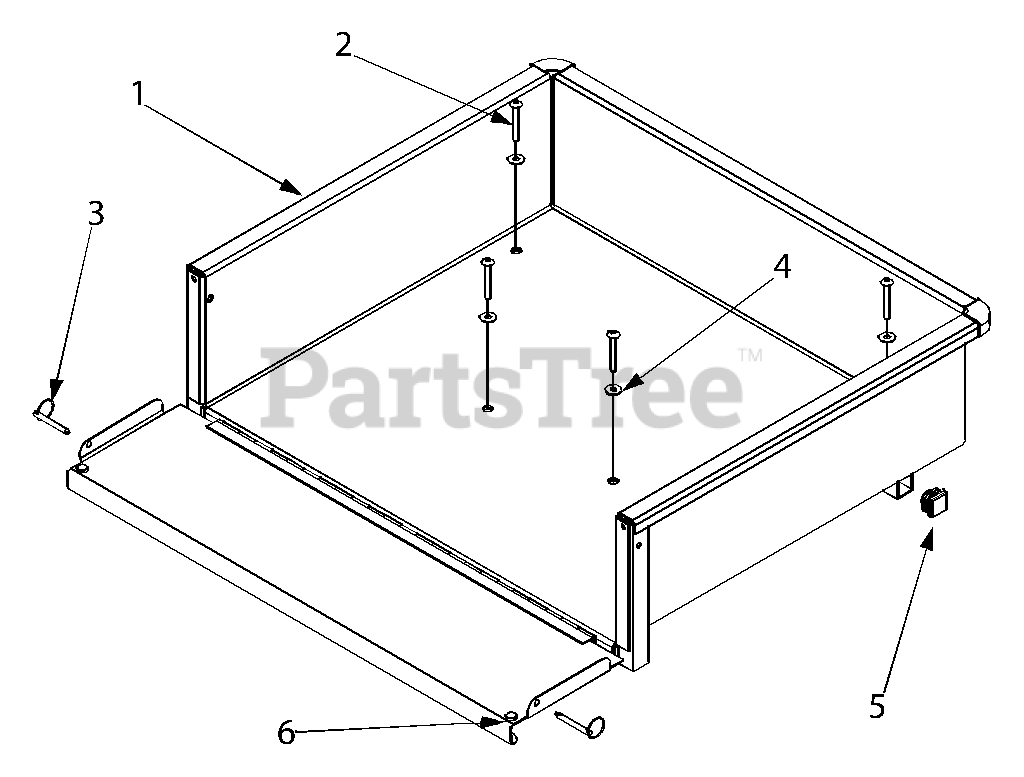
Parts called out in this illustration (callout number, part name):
1	Utility Box
2	Machine Screw 1/4-20 x 2"
3	Quick Release Pin
4	Flat Washer .28 ID x .74 OD
6	Rubber Bumper
